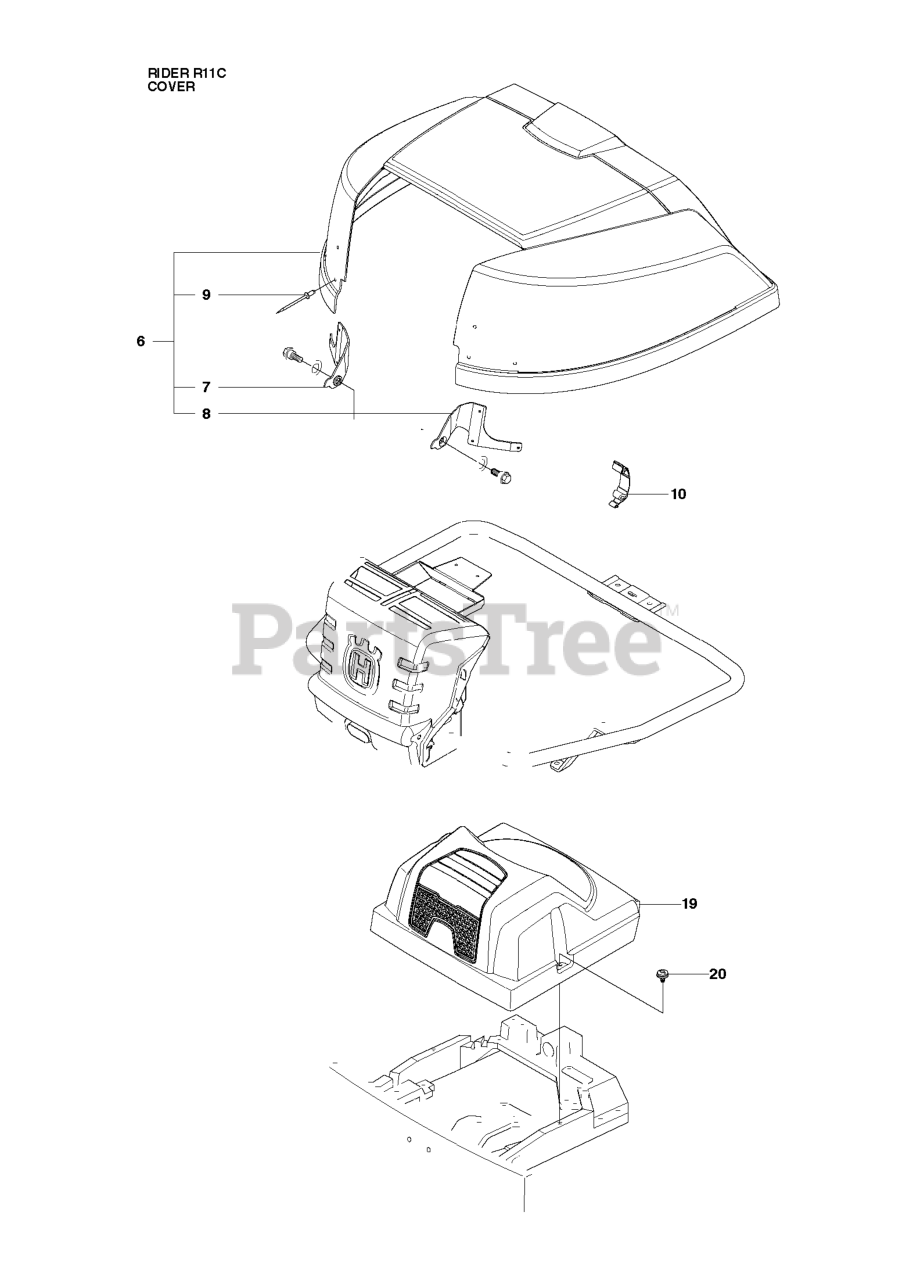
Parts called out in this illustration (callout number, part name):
7	HINGE LEFT
8	HINGE RIGHT
10	CLIP GRAY
19	RP COVER
